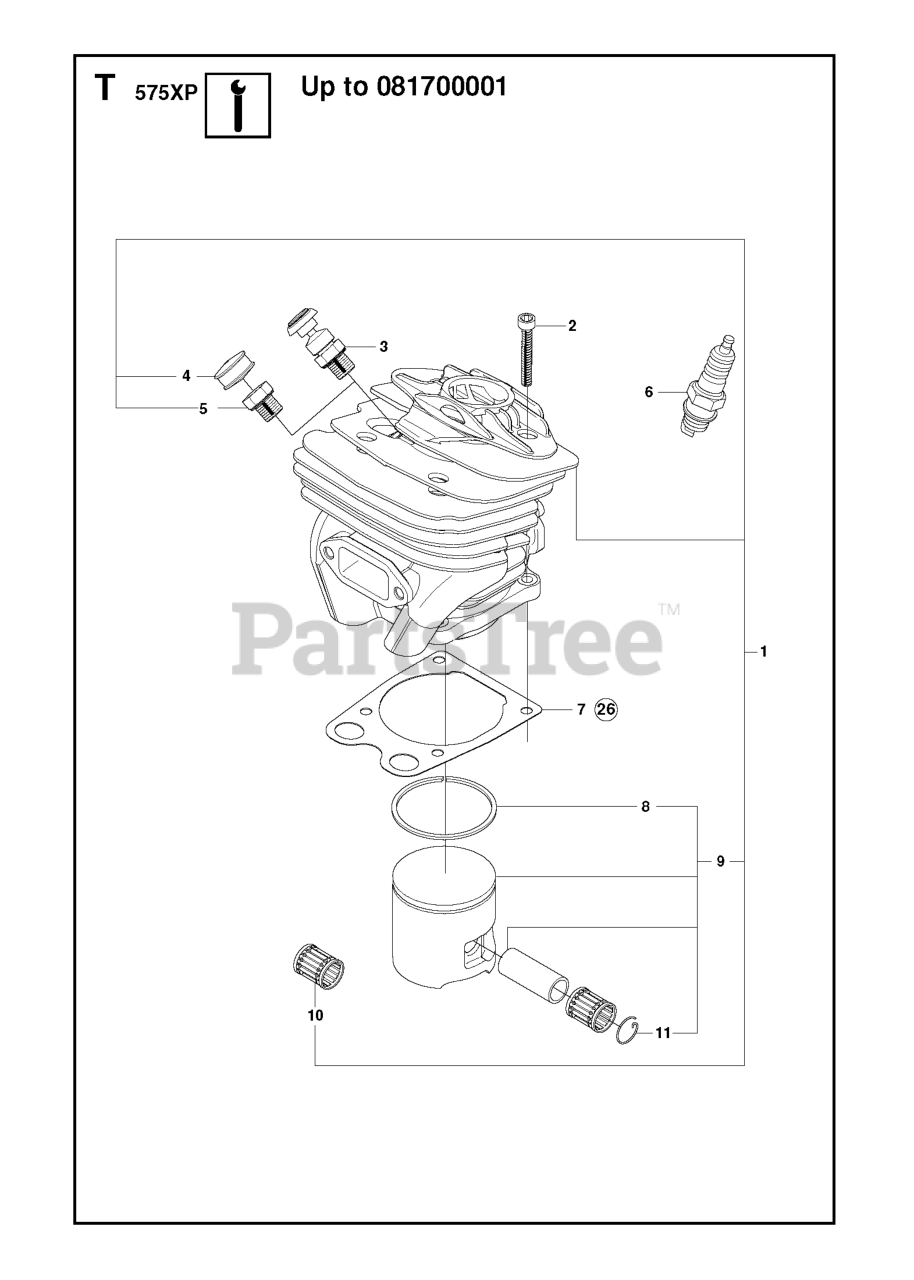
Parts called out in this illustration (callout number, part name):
1	%CYLINDER
2	SCREW MC6S 5X25
3	VALVE
5	CYLINDER PLUG
6	SPARK PLUG M14X1.25 NGK BPMR7A
8	PISTON RING
9	PISTON 49 MM
10	SUPPORT BUSHING
11	WRIST PIN CLIP
26	GASKET SET
